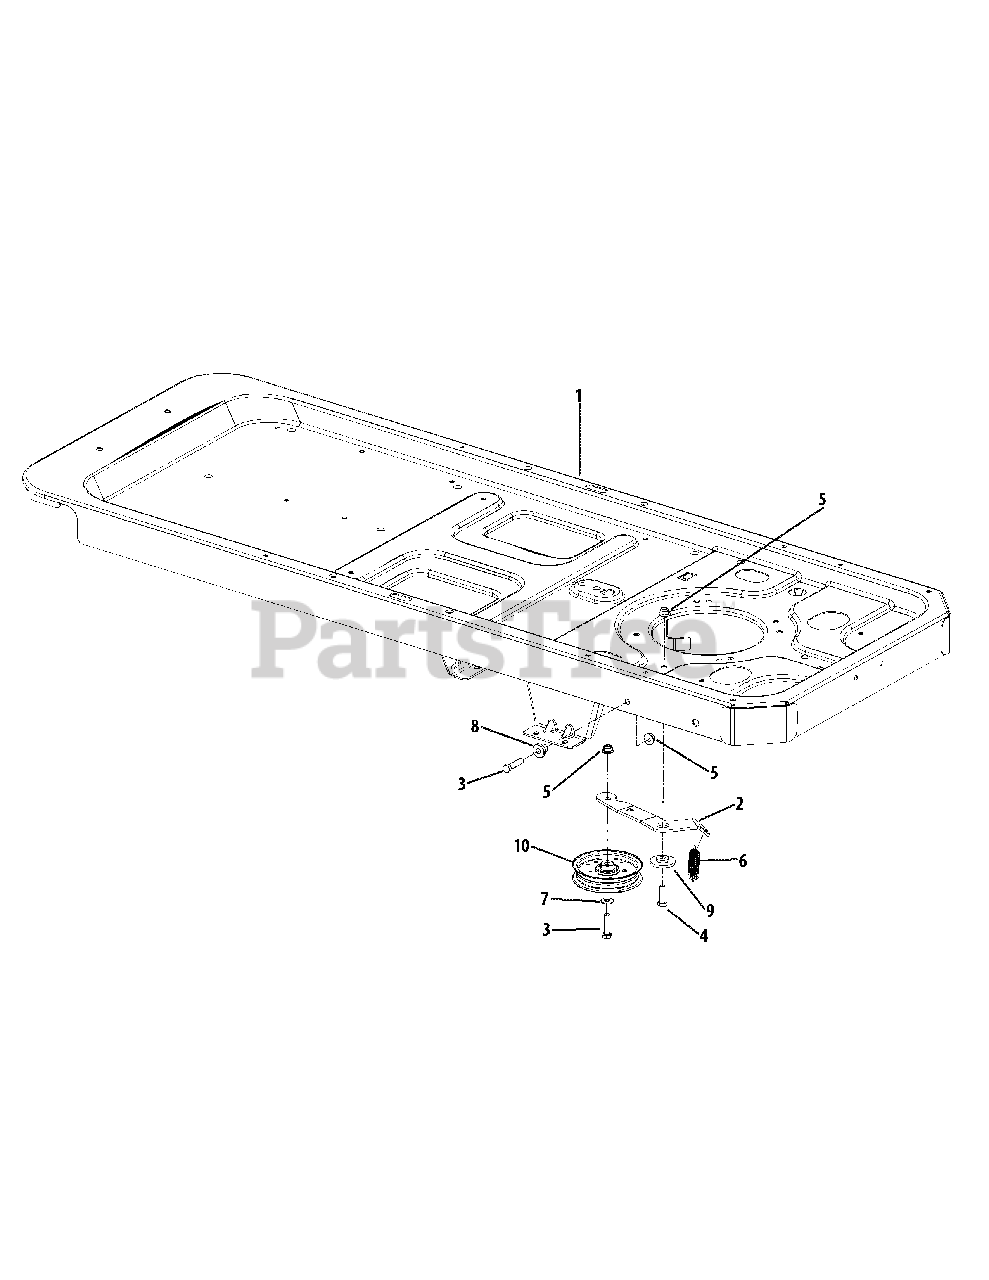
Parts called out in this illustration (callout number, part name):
1	Frame Assembly
2	Drive Idler Arm
3	Hex Screw, 3/8-16 x 1.5
4	Hex Screw, 3/8-16 x 1.25
5	Flange Nut, 3/8-16
6	Extension Spring, .75 x 5.06
7	Flat Washer, .408 x .875 x .059
8	Shoulder Spacer, .39 x 1.0 x .7
9	Shoulder Spacer, .884 x .19
10	Idler Pulley, 4.25 Dia.
